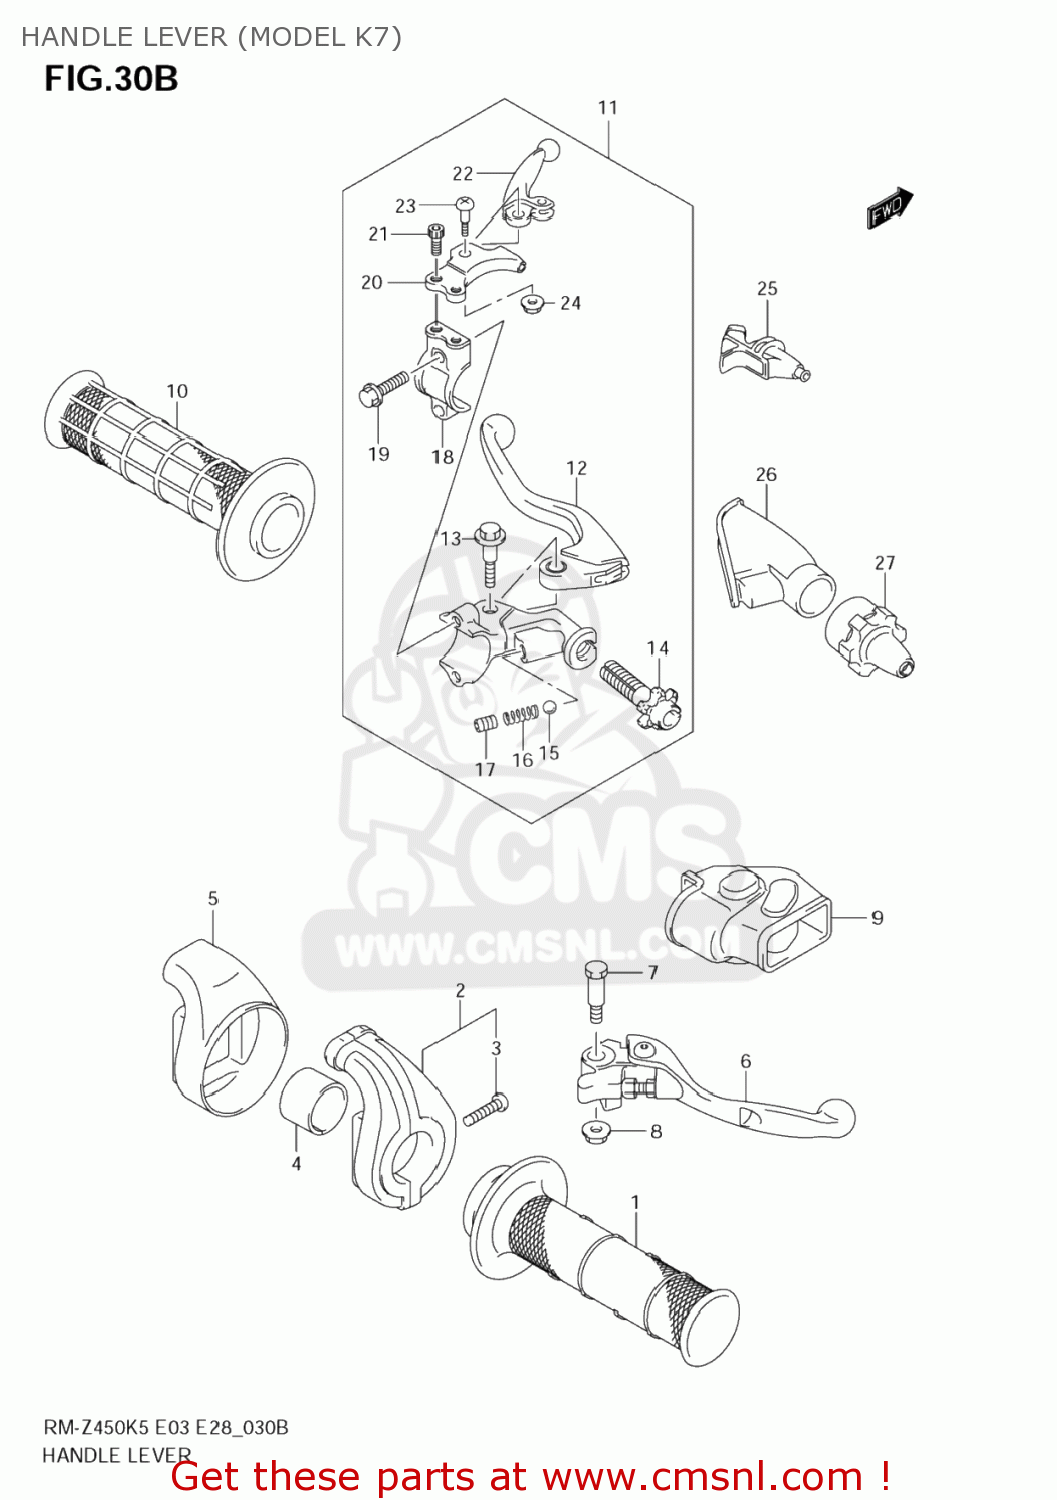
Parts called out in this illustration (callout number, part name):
1	GRIP COMP,THRO
2	CASE ASSY,THROTTLE
3	SCREW,CASE
4	COLLAR,THROTTLE CASE
5	COVER,THROTTLE CASE
6	LEVER ASSY,BRAKE
7	BOLT,BRAKE LEVER
8	NUT
9	COVER,BRAKE LEVER
10	GRIP,L
11	LEVER ASSY,CLUTCH
12	LEVER,CLUTCH
13	BOLT
14	ADJUSTER,CLUTCH CABLE
15	BALL
16	SPRING
17	SCREW(6X8)
18	HOLDER,CLUTCH LEVER
19	BOLT,BRACKET
20	HOLDER,HOT STARTER LEVER
21	SCREW(5X12)
22	LEVER,HOT STARTER
23	BOLT,HOT STARTER LEVER
24	NUT
25	COVER,HOT STARTER LEVER
26	COVER,CLUTCH LEVER
27	COVER,CLUTCH ADJUSTER
